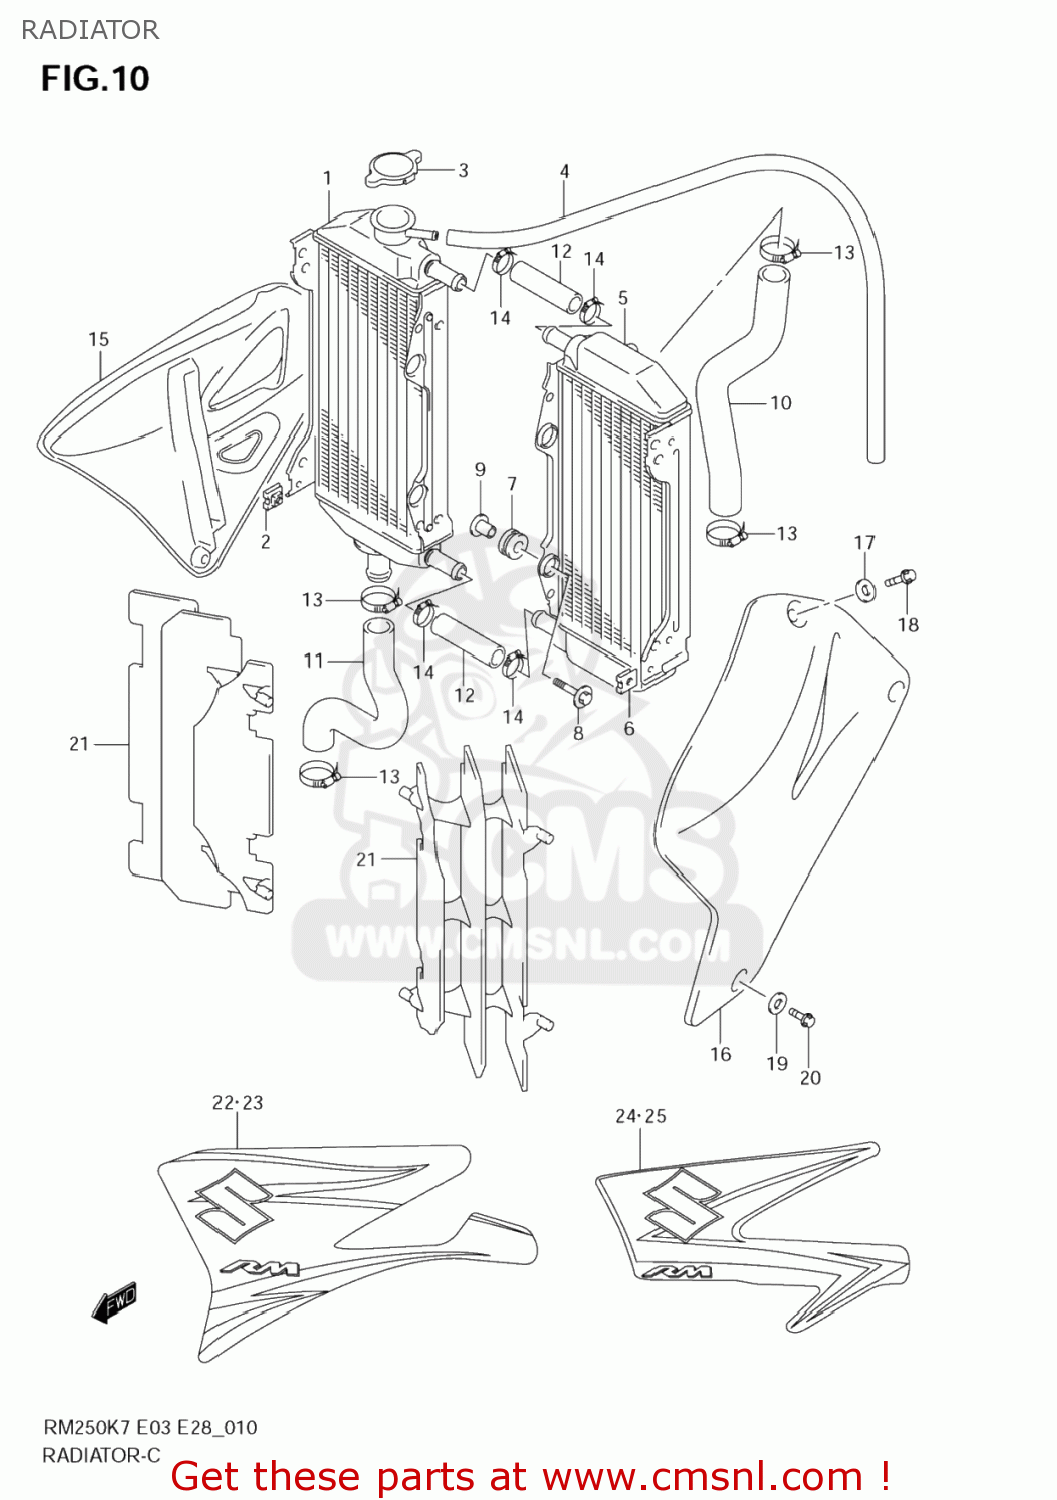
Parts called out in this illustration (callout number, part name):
1	RADIATOR,WATER,R
2	NUT
3	CAP COMP,RADIATOR
4	HOSE(5X8X1000)
5	RADIATOR,WATER,L
6	NUT
7	CUSHION,RADIATOR LWR
8	BOLT(6X25)
9	SPACER(6.5X10.5X14.1)
10	HOSE,RADIATOR INLET
11	HOSE,RADIATOR OUTLET
12	HOSE,RADIATOR JOINT
13	CLAMP
14	CLAMP
15	COVER,RADIATOR,R(YELLOW)
16	COVER,RADIATOR,L(YELLOW)
17	WASHER,RR BRAK
18	BOLT(6X12)
19	WASHER,RR BRAK
20	BOLT(6X12)
21	LOUVER,RADIATOR
22	TAPE,RADIATOR COVER,R
23	TAPE,RADIATOR COVER,L
24	TAPE,RADIATOR COVER,R
25	TAPE,RADIATOR COVER,L
